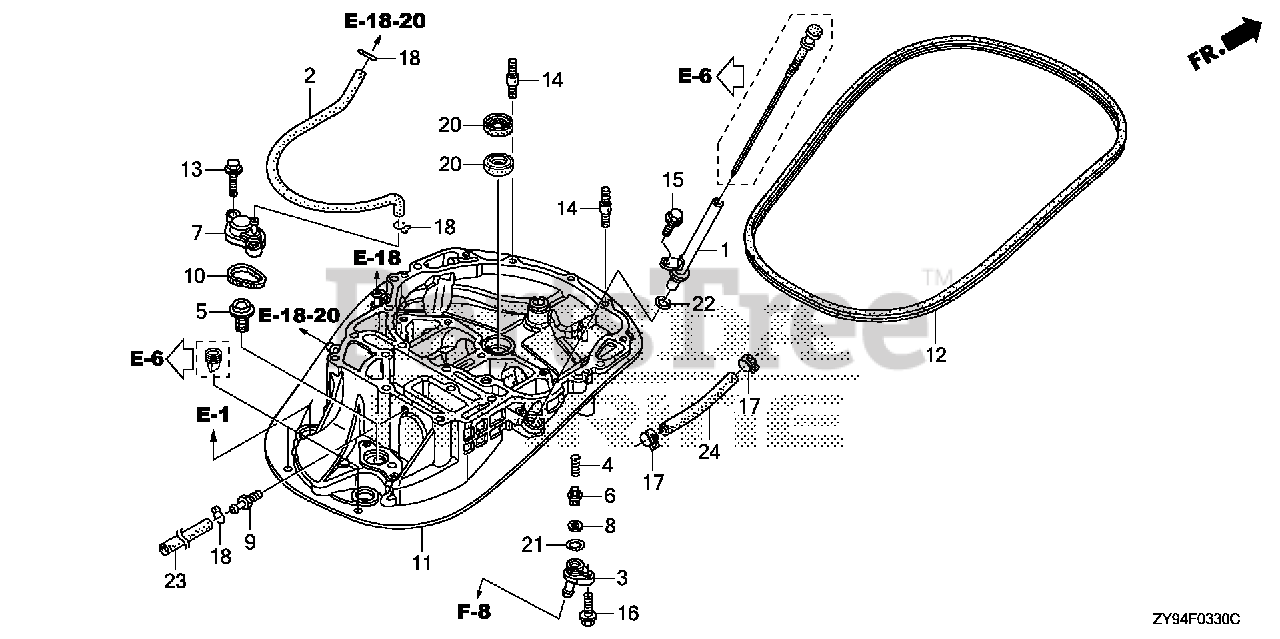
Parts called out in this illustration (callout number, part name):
1	PIPE, OIL LEVEL
2	TUBE B, WATER
3	COVER, FLUSH VALVE
4	SPRING, FLUSH VALVE
5	VALVE ASSY., RELIEF
6	VALVE, FLUSH
7	COVER, RELIEF VALVE
8	GASKET, FLUSH VALVE
9	JOINT, WATER TUBE
10	O-RING, THERMOSTAT COVER
11	CASE, MOUNT *NH8* (DARK GRAY)
12	SEAL A, COVER (LOWER)
13	BOLT, FLANGE (6X22)
14	BOLT, STUD (8X28)
15	BOLT, FLANGE (6X12)
16	BOLT, FLANGE (6X20) (ENGINE NO.)
17	CLAMP, TUBE (D10.5) (ENGINE NO.)
18	CLIP, TUBE (B10)
20	SEAL, WATER (22X35X7)
21	O-RING (16MM)
22	O-RING (11.5X3.5)
23	TUBE, WATER CHECK
24	BULK HOSE, VACUUM (7X3000) (7X550)
